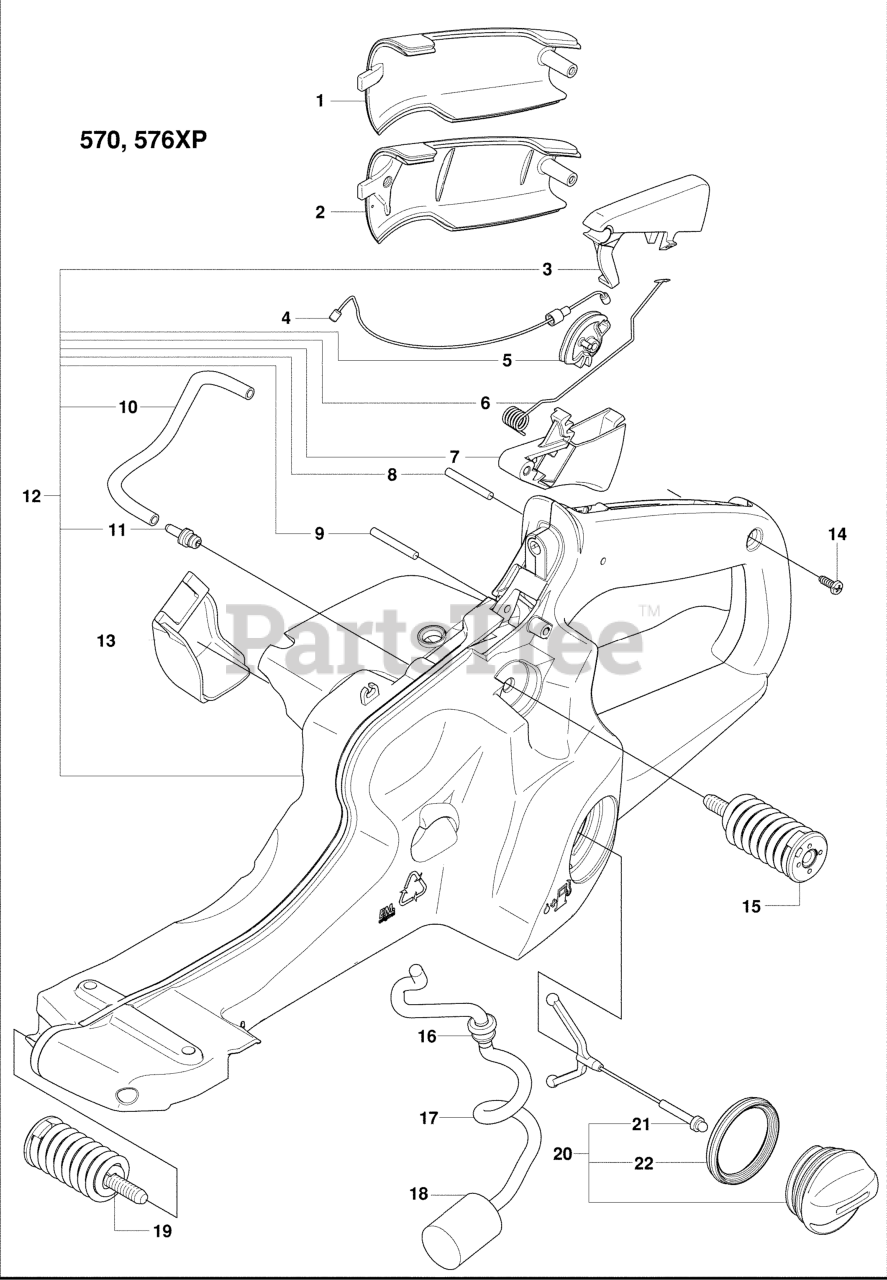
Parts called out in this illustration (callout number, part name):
1	COVER
2	COVER
3	THROTTLE LOCK
4	THROTTLE WIRE
7	THROTTLE TRIGGER
8	PIN 3X25
9	PIN 3X25
10	HOSE
11	FUEL TANK VENT
15	VIBRATION ABSORBER
16	FUEL TANK BUSHING
17	FUEL HOSE
18	RP FUEL FILTER
19	VIBRATION ABSORBER
20	TANK CAP
22	SEALING
